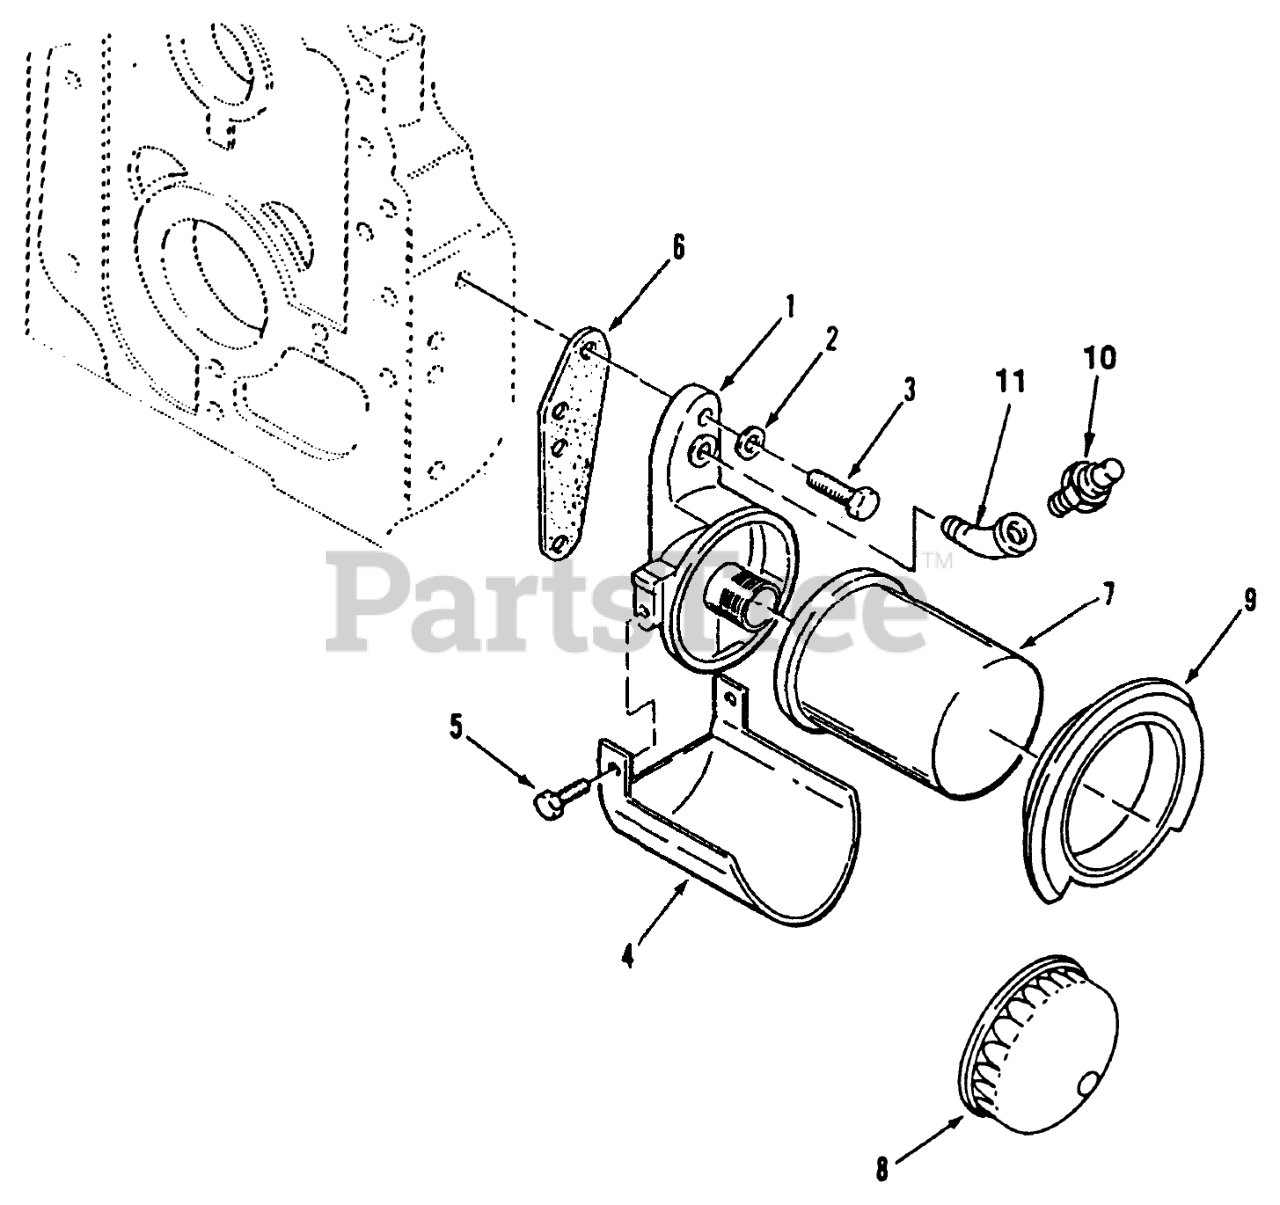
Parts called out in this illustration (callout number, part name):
1	ADAPTER-OIL FILTER
2	WASHER
3	HHCS 5/16-18 X 1
4	OIL-FILTER DRAIN
5	SCREW-HH
6	Gasket
7	OIL FILTER
8	Wrench
9	GASKET - AIR SEAL
10	SWITCH
11	45 DEG STREET ELBOW
